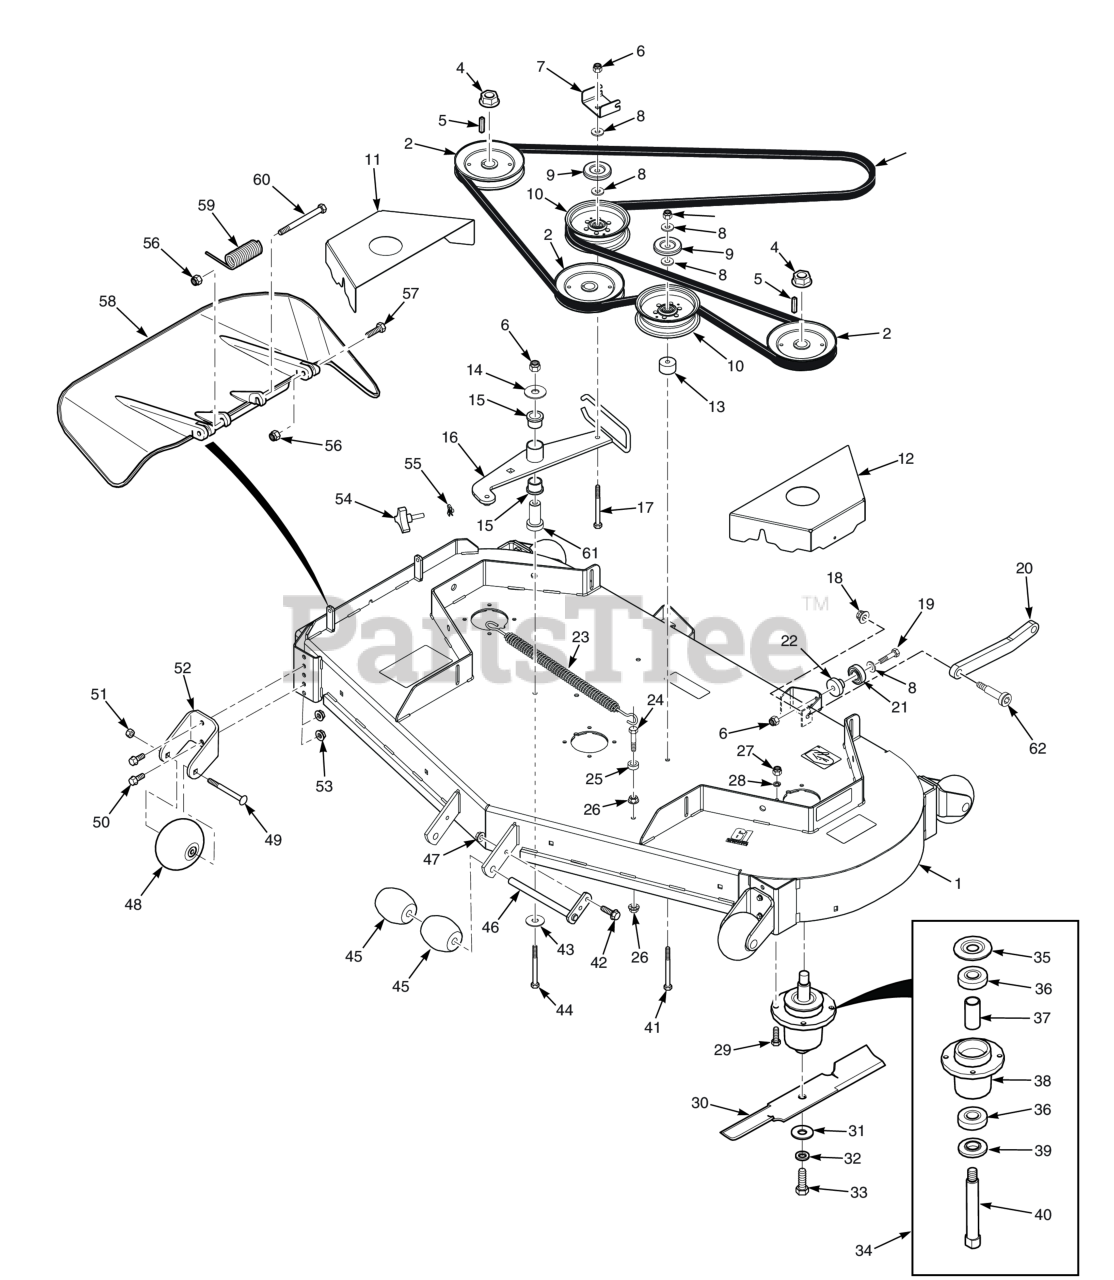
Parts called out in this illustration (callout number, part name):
1	Cutter Deck w/Decals, SWZT61
2	Pulley, 6.32" OD - 25mm Bore
3	Belt, Cutter Deck - SWZT61
4	Nut, 3/4-16 Spriral Lock
5	Key, 1/4 x 1/4 x 1.25" Pulley Mtg.
6	HEX NUT, ELASTIC STOP LOCK, 3/8-16
7	Bracket, Belt Guide
8	Flatwasher, 3/8 (.391 x .938 x .105 HD) Grade 8
9	Quick Pin, 5/16" Dia.
10	Pulley, 5" Idler
11	Belt Cover, RH - SWZT61
12	Belt Cover, LH - SWZT61
13	Spacer, Idler Pulley
14	Flatwasher, 3/8-.406 x 1-1-1/2 x 7 Gauge
15	Bearing, Plastic
16	Idler Arm Weldment w/Bearings - SWZT61
17	Capscrew, Hex Head 3/8-16 x 2-1/2"
18	Nut, Flange Elastic Stop Nut, 3/8-16
19	Bolt, Hex Head 3/8-16 x 1-3/4" (Kohler EFI)
20	Pusharm
21	Bearing
22	Spacer, Bearing
23	Spring, Cutter Deck Idler
24	Bolt, Hex Head 3/8-16 x 1-1/2" Grade 8 Black
25	SPACER, IDLER
26	NUT, 3/8-16 SERRATED FLANGE HEX HEAD
27	Lock Nut, 5/16-18 Elastic Stop Grade 8
28	Lockwasher, 5/16 (.317 x .586 x .078) Helical Spring
29	Bolt, Hex Head 5/16-18 x 1-1/2" Grade 8
30	Cutter Blade, 21" Standard
31	Flatwasher, 5/8-.688 x 1-3/4 x .134 HD
32	Lockwasher, 5/8" Spring
33	Bolt, Hex Head 5/8-11 x 1-1/2"
34	Spindle Assembly
35	Debris Shield
36	Bearing
37	Spacer, Bearing
38	Spindle Housing Assembly
39	Protector, Bearing
40	Shaft, Spindle
41	Bolt, Hex Head, 3/8-16 x 3-1/2"
42	Bolt, Heax Head 5/16-18 x 1" (48V / 52V)
43	Flatwasher, 3/8-.406 x 2.25" x .1875
44	Capscrew, Hex Head 3/8-16 x 3-3/4"
45	Wheel, Anti-Scalp
46	Shaft Weldment, Guide Roller
47	Nut, Flange Head Elastic Stop 5/16-18
48	Bolt, Carriage 3/8-16 x 4"
49	Bolt, Hex Head 3/8-16 x 3-1/2"
50	Capscrew, 3/8-16 x 1.0" Serrated Flange Hex Hd
51	Bolt, Hex Head 3/8-16 x 1" Ser. Flg.
52	Bracket, Anti-Scalp Wheel
53	NUT, 3/8-16 SERRATED FLANGE HEX HEAD
54	Knob, w/stud 3/8-16 x 1-1/4"
55	U-Nut, 3/8-16
56	HEX NUT, ELASTIC STOP LOCK, 5/16-18
57	Bolt, Hex Head 5/16-18 x 1-1/2" - Front
58	Discharge Chute Assembly
59	Spring, Discharge Chute
60	Bolt, 5/16-18 x 4-3/4" Hex Head
61	Pivot, Idler
62	Bolt, Shoulder 1/2 x 3/8-16 x 2-3/4"
